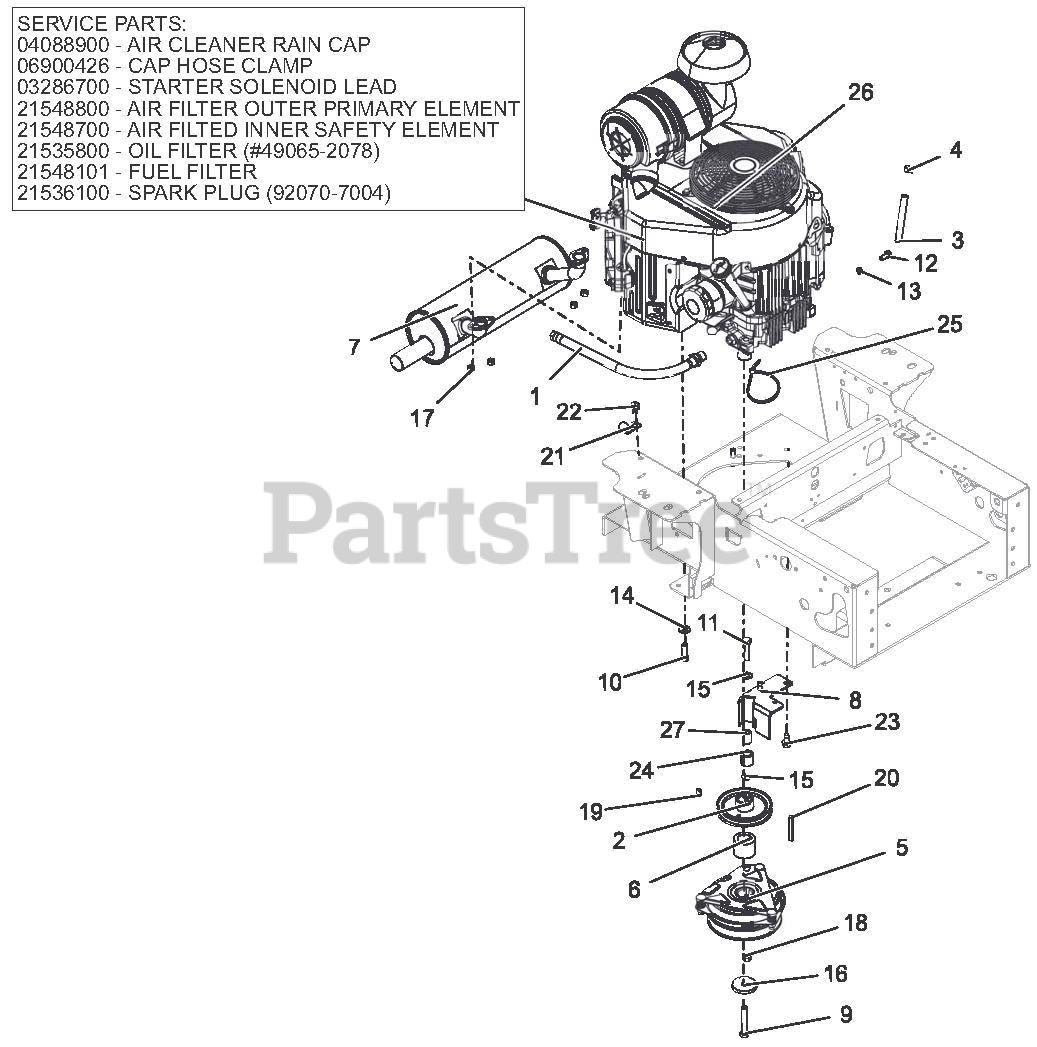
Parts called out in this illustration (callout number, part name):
1	HOSE, OIL DRAIN
2	PULLEY, 4.50 OD X 1.127 ENGINE - BLACK
3	.25 LOW-PERM GAS HOSE 25.00" LG - VALVE TO ENGINE
4	CLAMP, FUEL LINE
5	CLUTCH, OGURA GT2.5-FE02
6	SPCR, 1.125 X 1.75 X 1.400
7	MUFFLER, KAWASAKI FX24/26 HP
8	BRKT, CLUTCH STOP
9	BLT-HEX .44-20 X 2.50 GR5 EP 80 YWZC
10	BLT-HEX .38-16 X 1.25 GR5 YWZC NYTORQ
11	BLT-HEX .38-16 X 1.75 GR5 YWZC
12	@BLT-HEX M8-1.25 X 20 YWZC
13	WSHR-LK .31 X .078 REG YWZC
14	WSHR, 3/8" SPRING DISC
15	WSHR-FL-STL .406 X .812 X .065 YWZ
16	WSHR-FL-STL .469 X 2.00 X .25 YWZC
17	NUT-LK-TOP M8-1.25 YWZC
18	NUT, LK-TOP-FLG .38-16 YWZC
19	KEY-SQ .250 X .250 X .625
20	KEY, .25 X .25 X 2.25
22	SCR-TAP .38-16 X .50 HWH TR YWZ
23	SCR-TAP .38-16 X .75 HWH TR YWZ
24	BUMPER, RUBBER .62 X 1.0 X .88 LG
25	CABLE, TIE 5.50 LG
26	ENGINE, KAWASAKI FX730
26	AIR CLEANER RAIN CAP
26	CAP HOSE CLAMP
26	STARTER SOLENOID LEAD
26	AIR FILTER OUTER PRIMARY ELEMENT
26	AIR FILTER INNER SAFETY ELEMENT
26	OIL FILTER - #49065-2078
26	FUEL FILTER
26	SPARK PLUG - #92070-7004
27	BUSH., S .391 X .622 X .95 ST REV A
